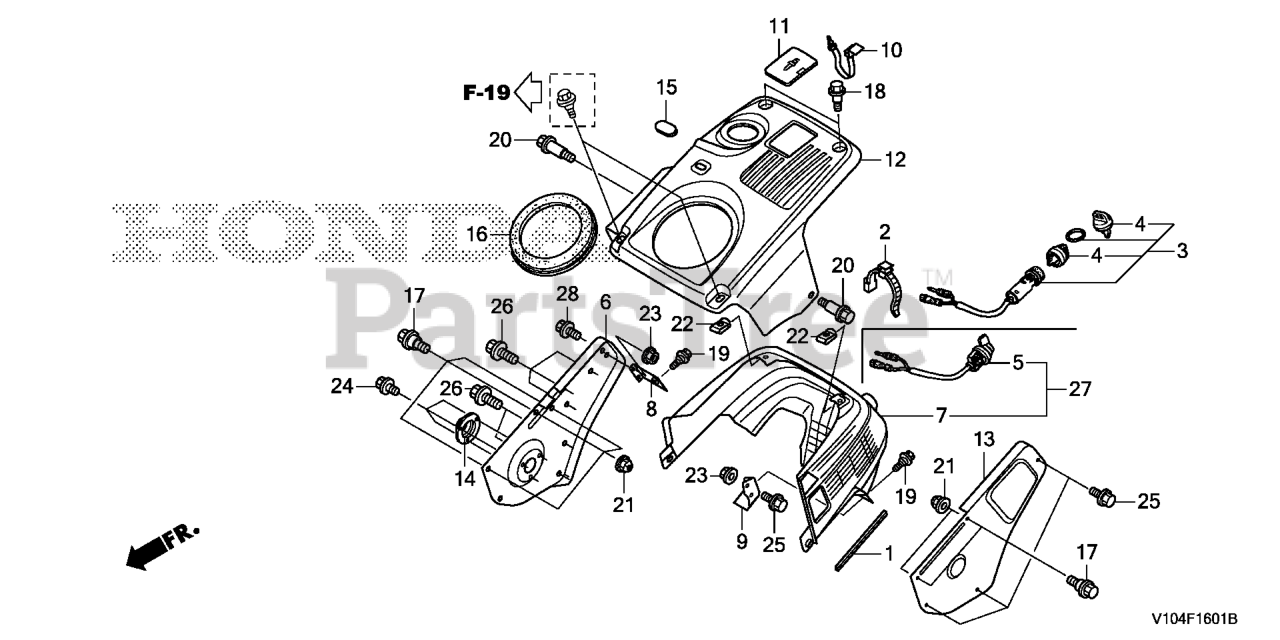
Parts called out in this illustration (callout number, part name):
1	SEAL KIT, COVER
2	TIE, CABLE
5	SWITCH ASSY., ENGINE STOP
6	COVER, R. SIDE
7	COVER, RR.
8	BRACKET, R. RR. COVER
9	BRACKET, L. RR. COVER
10	KNOB, PLUG COVER
11	COVER, PLUG
12	COVER, TOP
13	COVER, BELT
14	HOLDER, R. AUGER (BEARING)
15	GROMMET, PLUG
16	RUBBER, CHUTE
17	BOLT, SIDE COVER
18	BOLT, CHUTE SETTING
19	BOLT, RR. COVER
20	BOLT, COVER SETTING
21	NUT, SELF-LOCK (6MM)
22	NUT, AIR SPOILER CLIP
23	NUT, FLANGE (6MM)
24	BOLT, FLANGE (6X10)
25	BOLT, FLANGE (6X12)
26	BOLT, FLANGE (8X16)
27	COVER KIT, RR.
28	BOLT, FLANGE (6X12)
28	BOLT, FLANGE (6X14)
